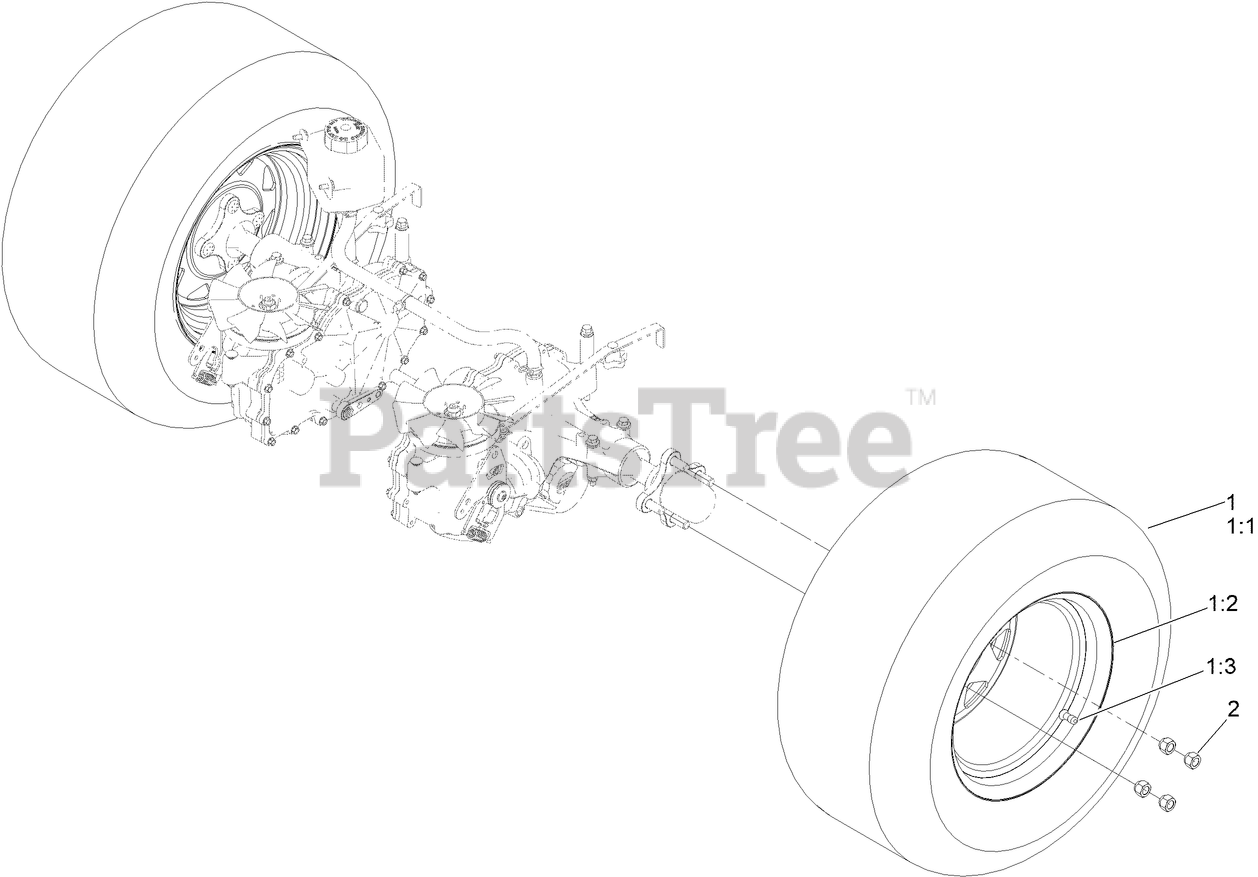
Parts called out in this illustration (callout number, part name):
1	WHEEL AND TIRE ASM
1:1	TIRE-VOODOO
2	NUT-LUG
